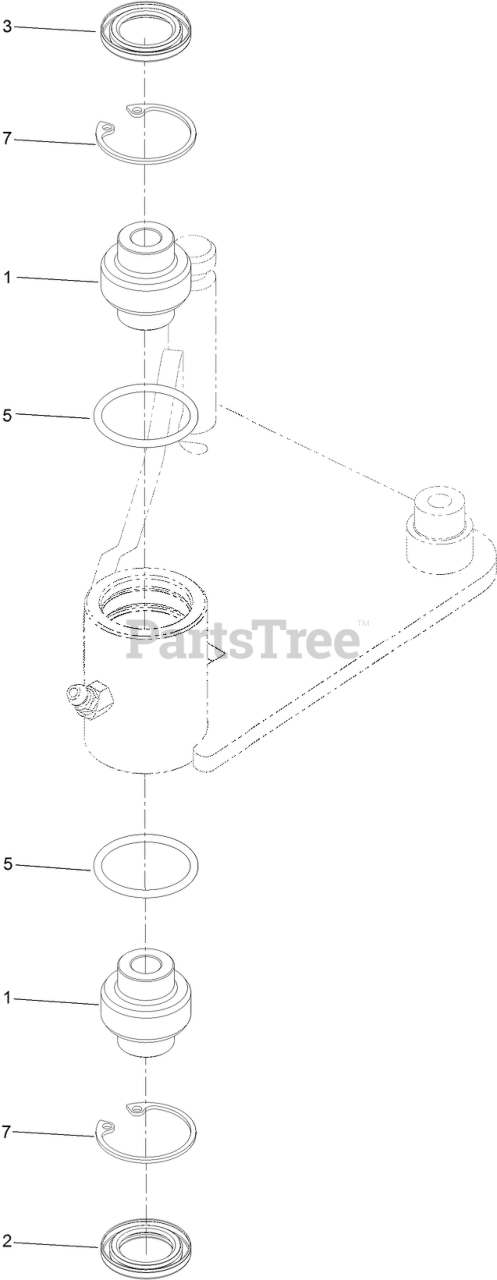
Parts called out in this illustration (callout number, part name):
1	BEARING-SPHERICAL
2	SEAL-LIP, DOUBLE
3	SEAL-LIP, SINGLE
7	RING-SNAP
